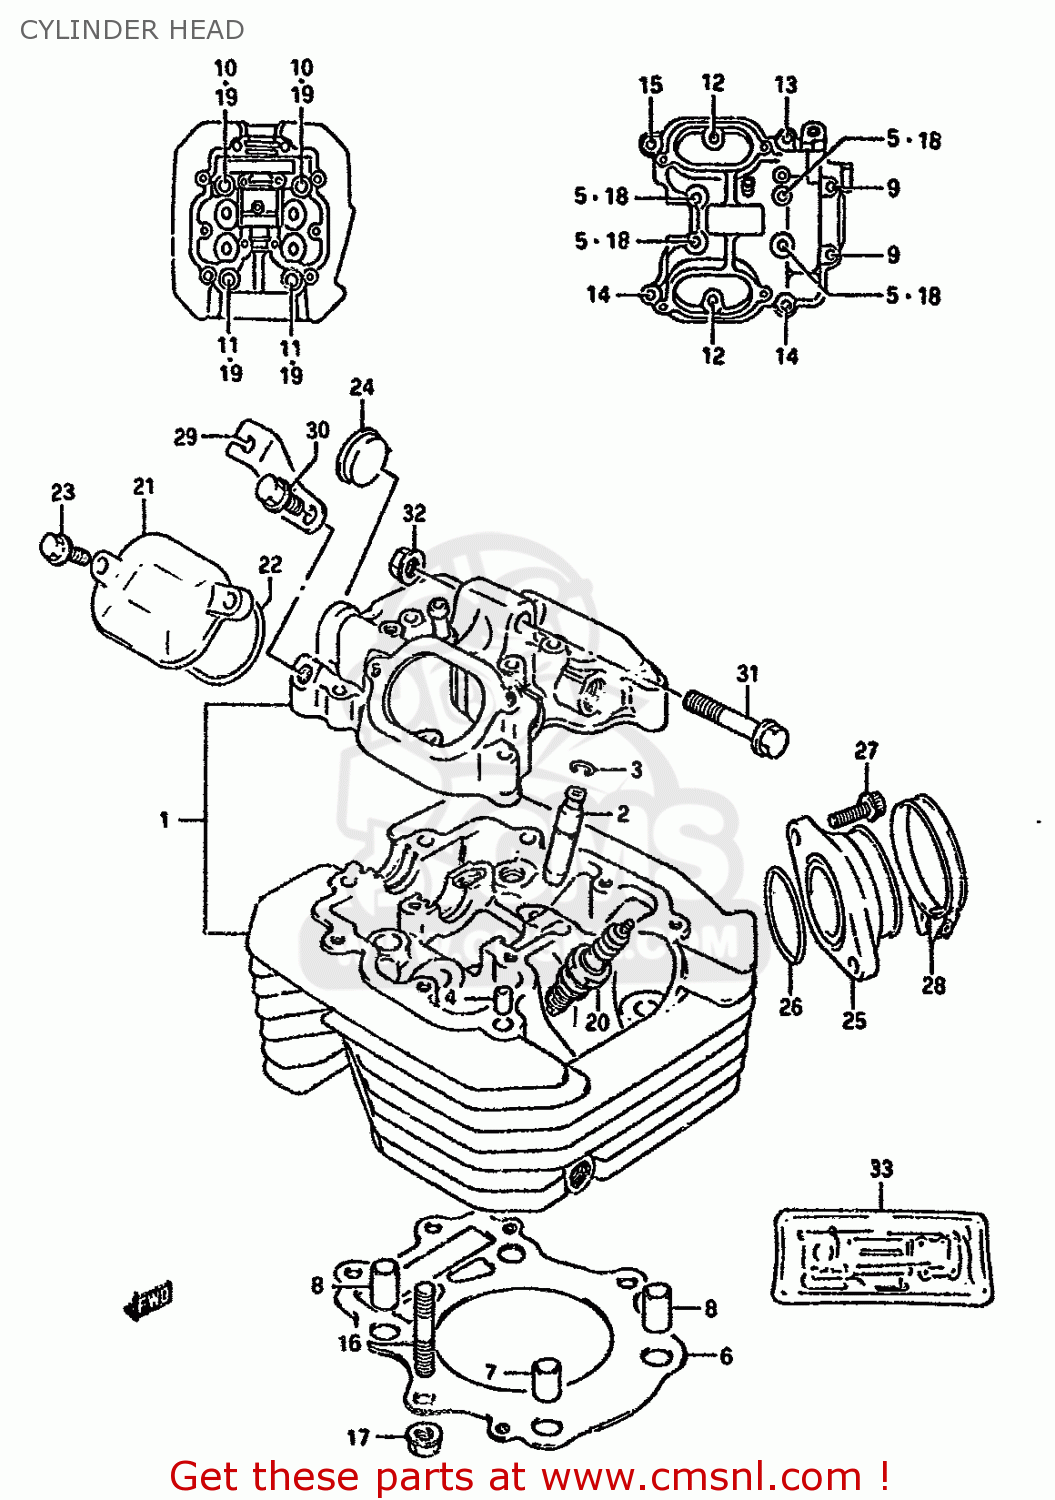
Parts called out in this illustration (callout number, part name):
1	HEAD ASSY,CYLINDER
2	GUIDE,VALVE
3	RING,SNAP
4	PIN(6.2X8X11)
5	BOLT(6X55)
6	GASKET,CYLINDER HEAD (NAS)
7	PIN
8	PIN(10.4X13X22)
9	BOLT(6X115)
10	BOLT(10X180)
11	BOLT(10X155)
12	BOLT
13	BOLT
14	BOLT(6X35)
15	BOLT(6X39)
16	BOLT,STUD
17	NUT
18	GASKET(5.8X13X1.2) (NAS)
19	WASHER (10.5X22X2.3)
20	PLUG,SPARK(CR9EK)
21	CAP,INSPECTION
22	GASKET (NAS)
23	BOLT
24	PLUG,OD:30
25	PIPE ASSY,INTAKE
26	O RING(D:2.4,ID:39.7)
27	BOLT
28	CLAMP
29	LEVER,DECOMP SHAFT RH
30	BOLT
31	BOLT(8X65)
32	NUT
33	GASKET SET (NAS)
